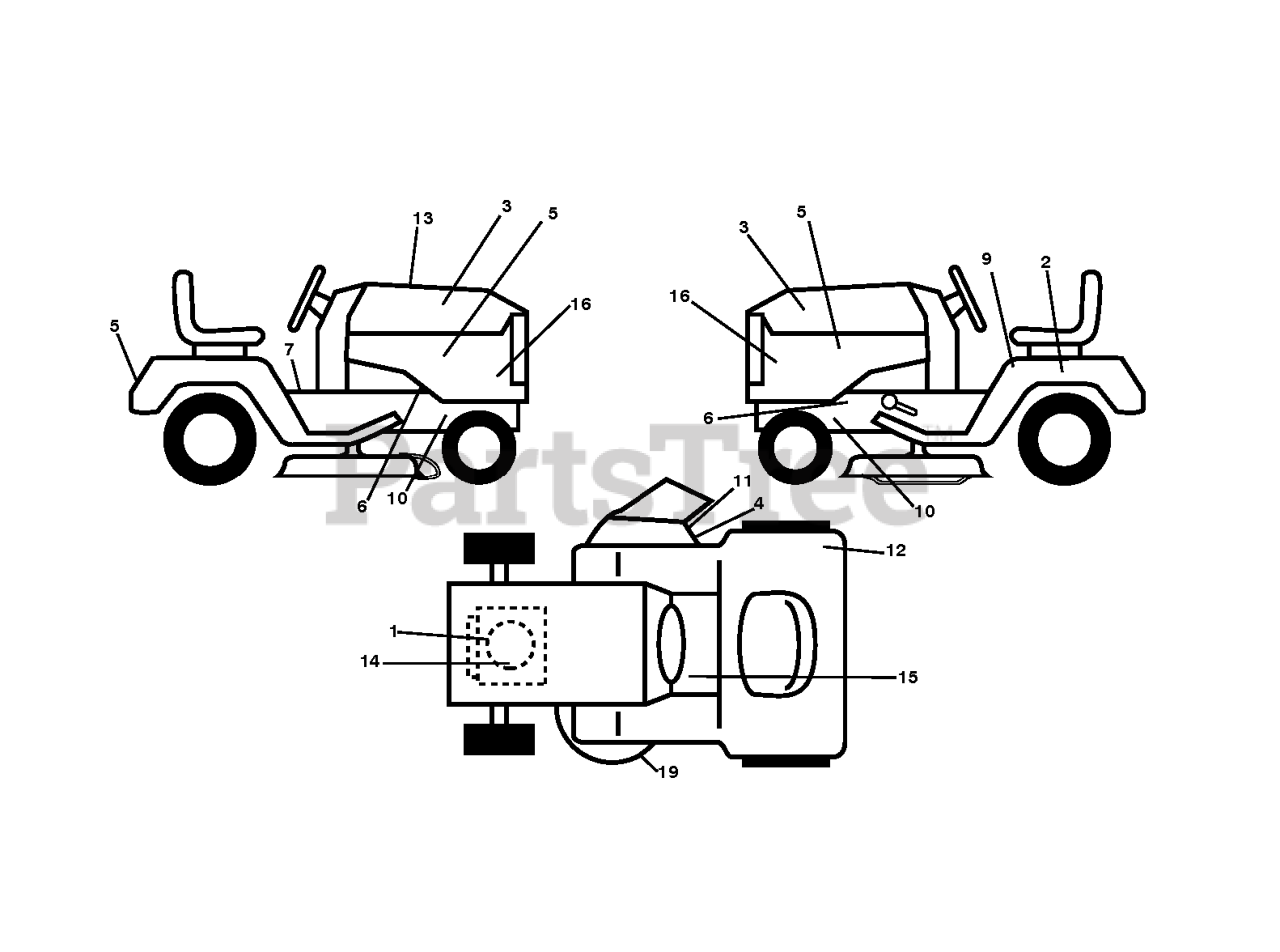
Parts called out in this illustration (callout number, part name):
1	DECAL
2	DECAL BTRY SYMBOLS
4	DECAL, DEFLECT WARNING
5	DECAL.HOOD.NAMELOGO.HUSQ
7	DECAL PARK BRAKE
9	LABEL
11	DECAL.INTERNATIONL.CUTFINGER
12	Decal, Fender 100 DB/CE
15	DECAL
19	DECAL.V-BELT.SCHEMATIC.36/38/9
